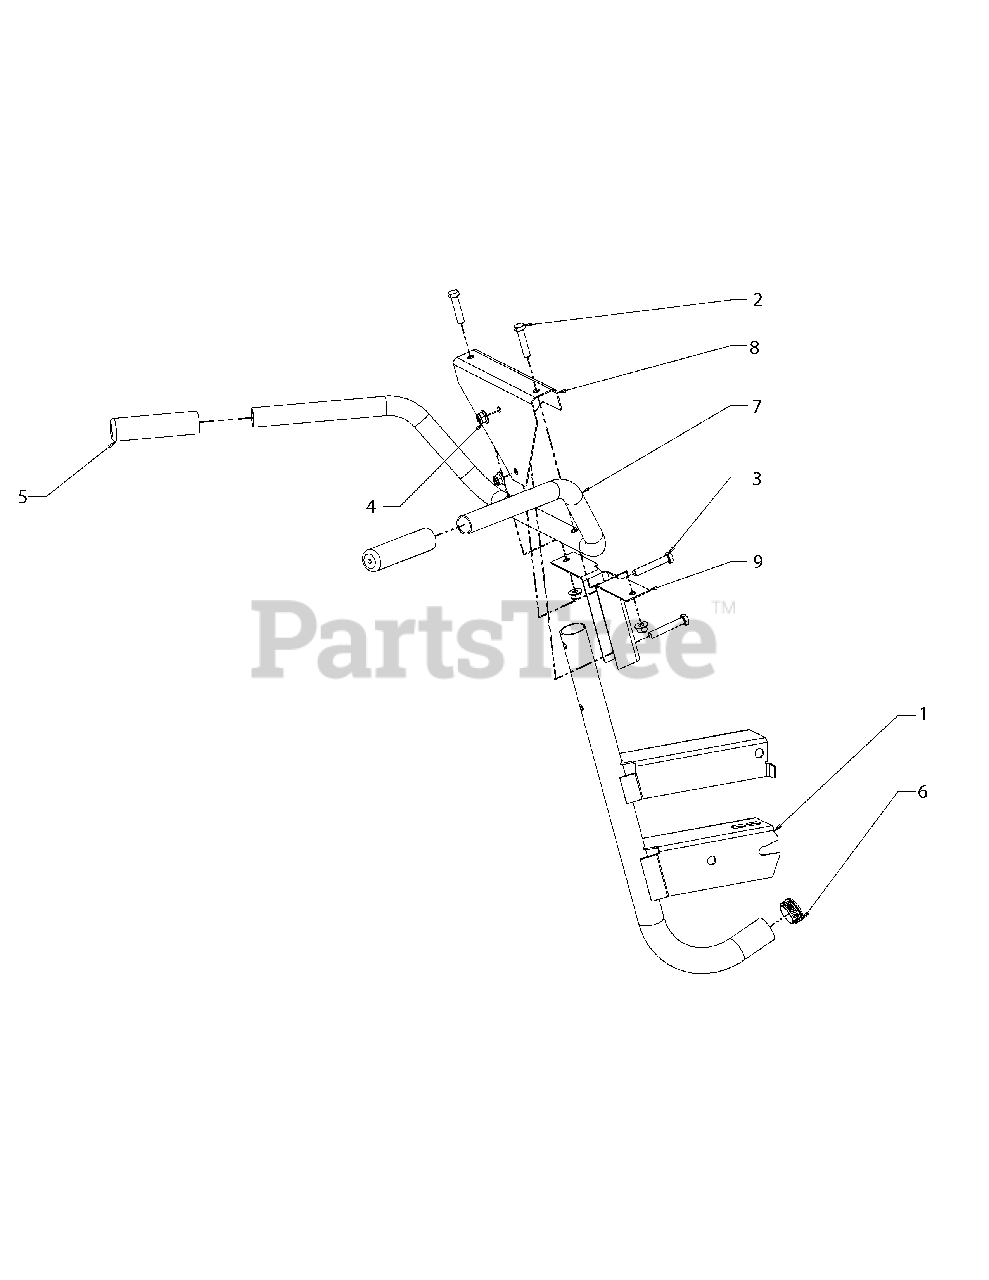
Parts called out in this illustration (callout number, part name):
1	Center Handle Tube Asm
2	Screw-Hex 3/8-16 X
3	Screw-3/8-16 X 2.2
4	Nut-Flange Lk.Nylo
5	Grip-Lapbar 1.125
6	Bumper Cap
7	Top Handle
8	Bracket Mount:Top-Handle
9	Bracket Mount:Center-Handle
